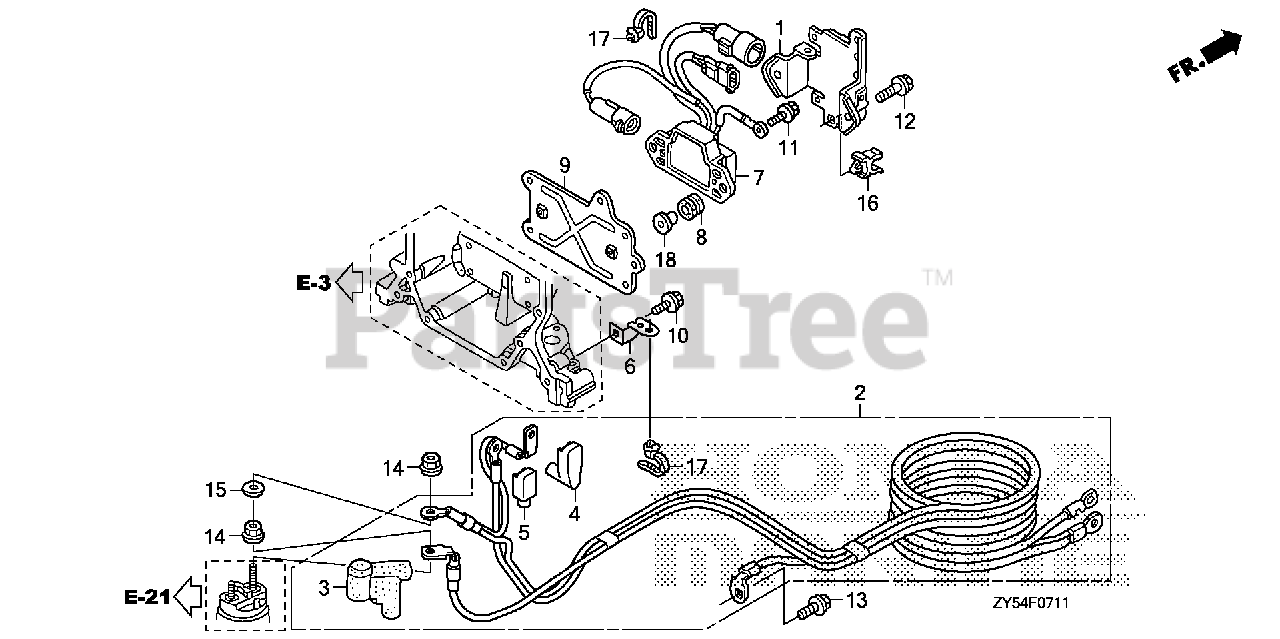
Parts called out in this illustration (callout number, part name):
1	BRACKET A, CONNECTOR
2	CABLE ASSY., STARTER
3	COVER, STARTER TERMINAL
4	COVER B, TERMINAL (L)
5	COVER B, TERMINAL
6	BRACKET B, CABLE
7	RELAY ASSY., POWER TILT
8	GROMMET, RELAY
9	BRACKET, RELAY
10	BOLT, FLANGE (6X14) (CT200)
11	BOLT, FLANGE (6X12)
12	BOLT, FLANGE (6X22)
13	BOLT, FLANGE (8X18)
14	NUT-WASHER (8MM)
15	WASHER, PLAIN (8MM)
16	CLIP, FUEL TUBE (14) (NOT AVAILABLE)
17	CLIP, HARNESS BAND (145MM) (BLACK)
18	COLLAR, MODULE IGNITION CONTROL CASE (CDI)
